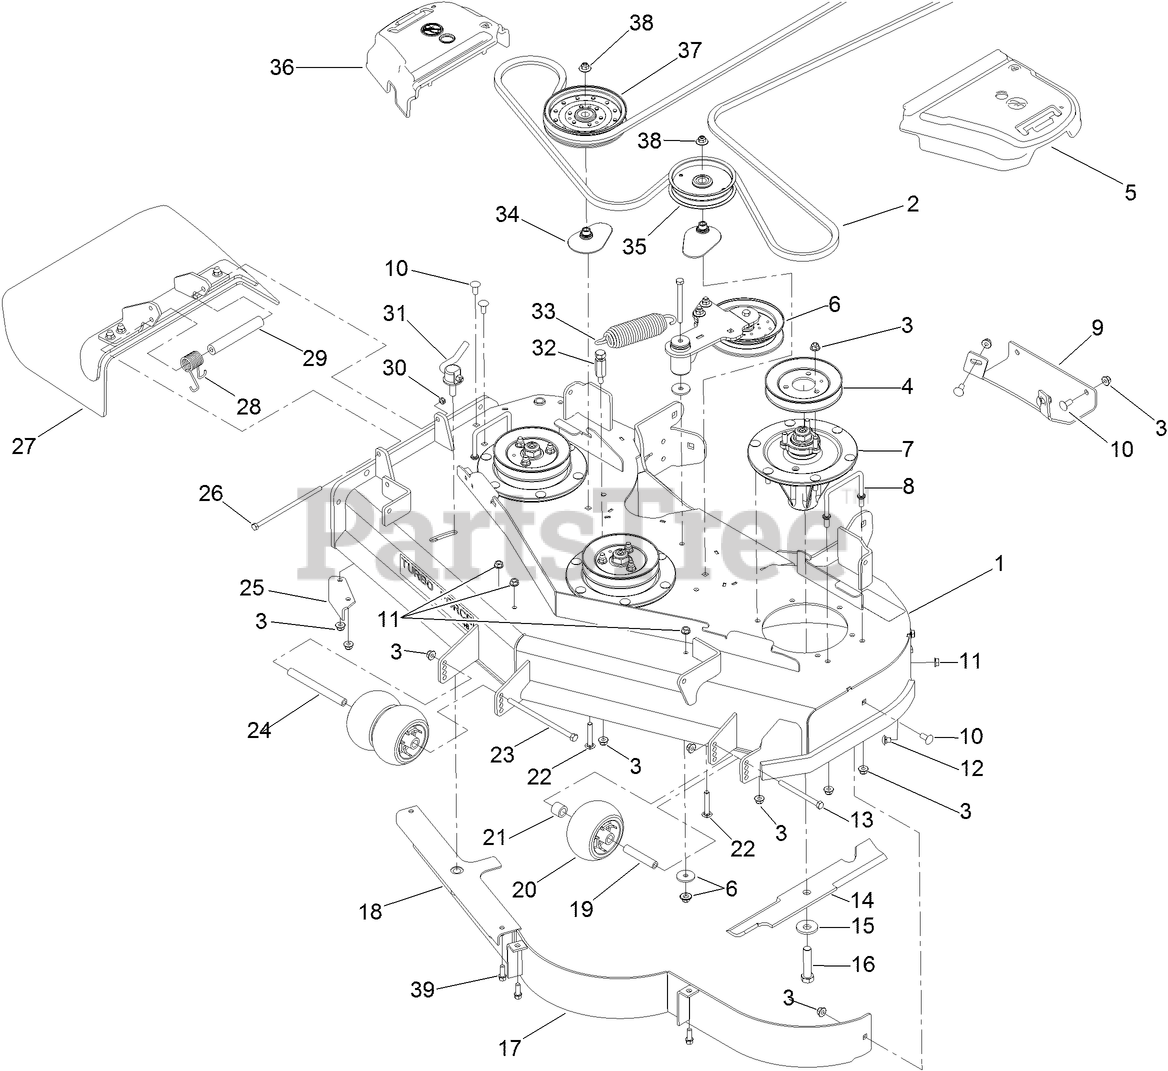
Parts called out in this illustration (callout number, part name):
1	DECK DECAL ASM
2	BELT-V
3	NUT-HF, NI
4	PULLEY
5	COVER-BELT, LH
6	IDLER ARM ASM
7	SPINDLE ASM
8	WIREFORM-COVER
9	PLATE-SKID
10	SCREW-CARR
11	NUT-HHF, WHIZ
12	SCREW-CARR
13	SCREW-HH
14	BLADE-16.5 INCH (HIGH FLOW)
15	Washer-Blade Bolt, Heavy
16	SCREW-BLADE
18	BAFFLE
19	TUBE-SPANNER
20	ROLLER-SCALP, ANTI
21	TUBE-SPACER
22	BOLT-CARR, SHORT NECK
23	SCREW-HH
24	SPACER-WHEEL
25	BAFFLE-DISCHARGE
26	SCREW-HH
27	RUBBER DEFLECTOR ASM
28	SPRING-TORSION
29	SPACER
30	NUT-LOCK, NI
31	LEVER ASM
32	ANCHOR-SPRING, TALL
33	EXTENSION-SPRING
34	SPACER-PULLEY
35	PULLEY-IDLER
36	COVER-BELT, RH
37	PULLEY-IDLER, FLAT
38	NUT-FLANGE, NI
39	SCREW-HWH
